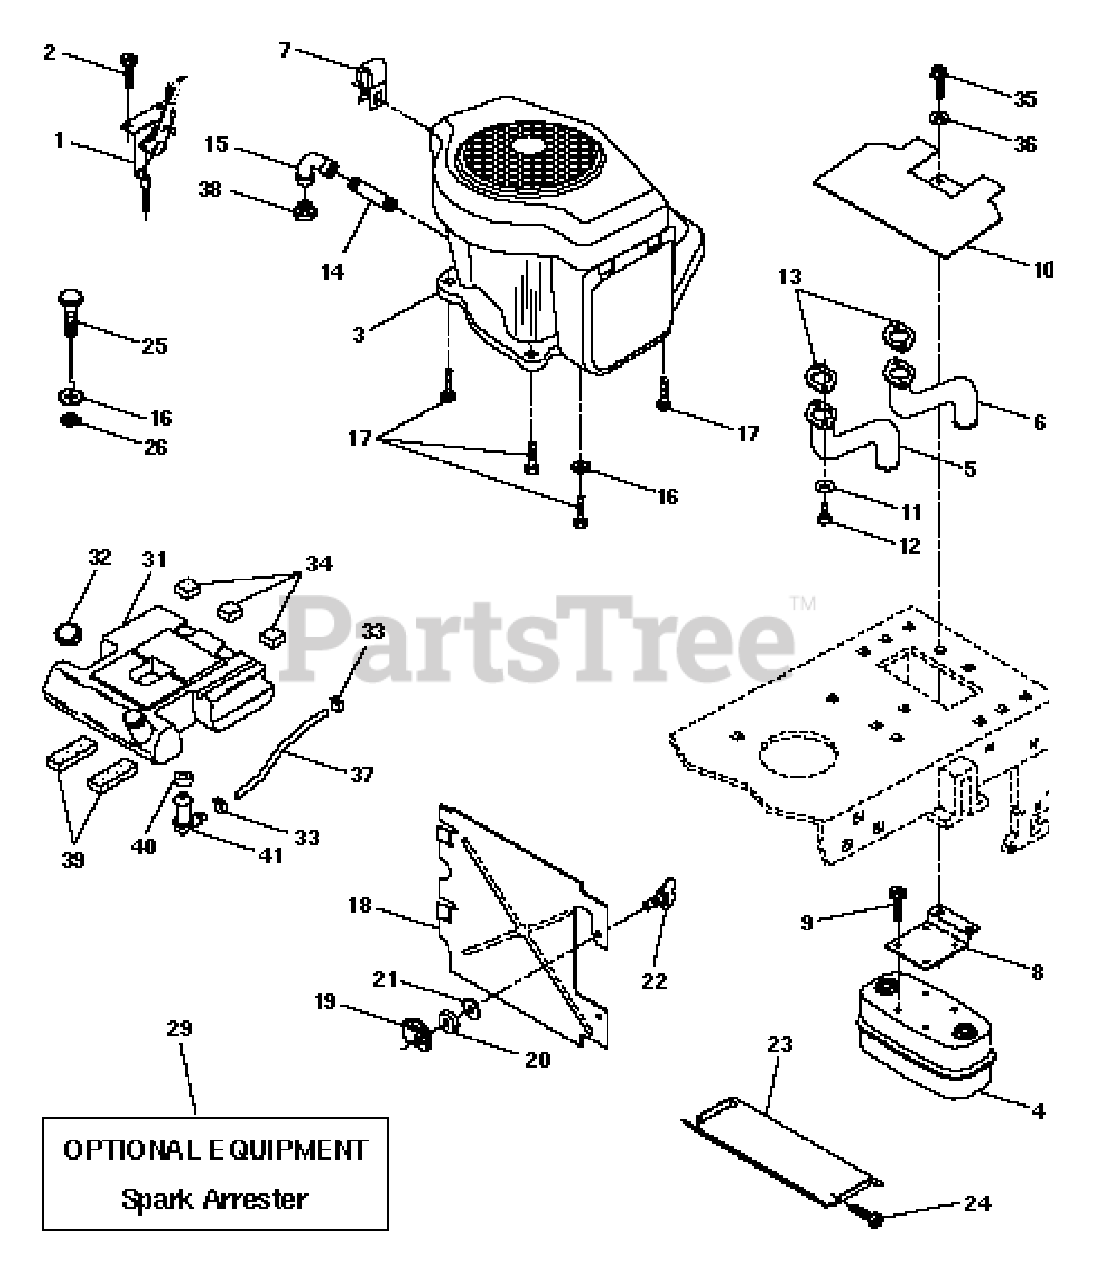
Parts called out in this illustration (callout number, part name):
1	Control RH Blk Flg 37 88
2	Screw Hex Thd Cut 1/4-20x5/8 T
4	Muffler LT B&S
5	Tube Manifold LH
6	Tube Manifold RH
8	Bracket Muffler Mounting
9	Screw Hex Wsh Thd Cut 1/4-20
10	Shield Heat LT
11	Washer Lock Hvy Hlcl 1/4
12	Bolt, Fin Hex 1/4-20 x 3/4
13	Muffler Gasket
14	Nipple Pipe 3/8 Npt X 4-1/2"
15	Elbow Std 90 Degree 3/8-18 Npt
16	Washer Lock Ext Tooth 3/8
17	Screw Thdrol 3/8-16 x 1-1/2
18	Shield Heat Mech
19	Receptacle 1/4 Turn
20	Retainer 1/4 Turn
21	Bushing, Snap, Split
22	Stud 1/4 Turn
23	Shield Heat Browning LT/YT
24	Screw Tap Hex #10-24unc X 1/2
25	Choke Control
26	Nut, Fin Hex 3/8-24 Unf
29	Kit Spark Arrestor (Flat Scrn)
31	Tank Fuel 3 50 Rear
32	Cap Asm Fuel W/sym Vented
33	Clamp Hose Blk
34	Pad, Spacer
35	Screw Thdrol 5/16-18 x 3/4
36	Washer 13/32 x 1-1/4 x 12 Ga.
37	Line Fuel 54"
38	Plug Oil Drain
39	Pad, Idler
40	Bushing
41	Stem Tank Fuel
